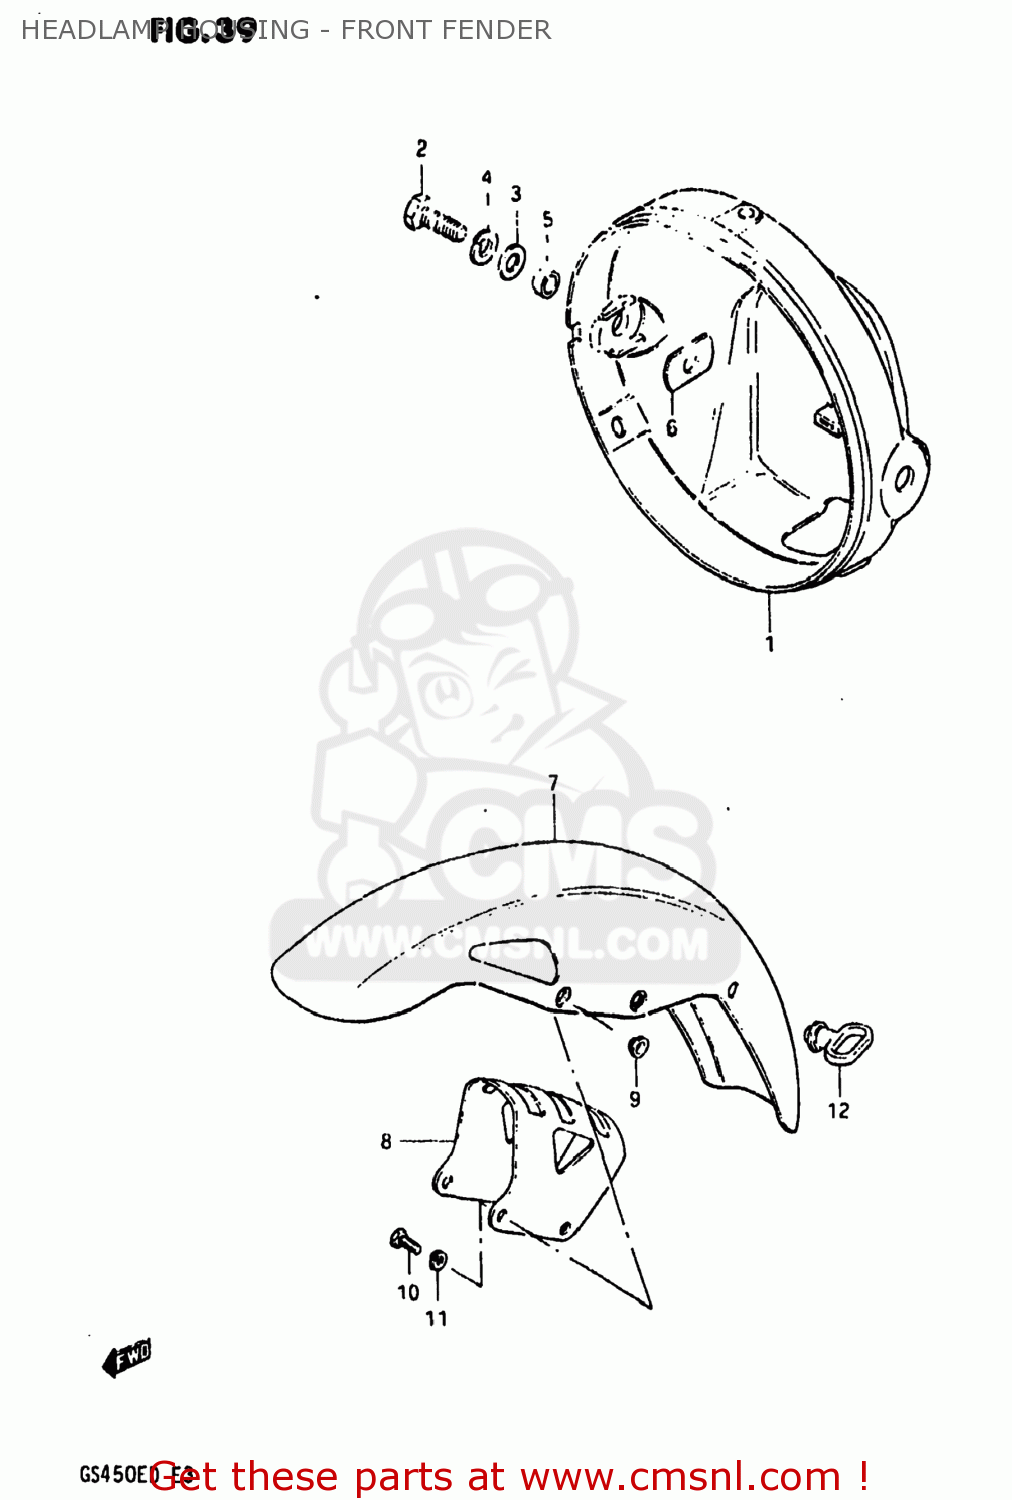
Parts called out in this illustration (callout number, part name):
1	HOUSING,HEADLAMP
2	BOLT
3	WASHER
4	LOCK WASHER
5	SPACER (8.8X12X7)
6	CUSHION
7	FENDER,FRONT
8	BRACE,FRONT FENDER
9	WASHER
10	BOLT
11	LOCK WASHER
12	GUIDE,CABLE
